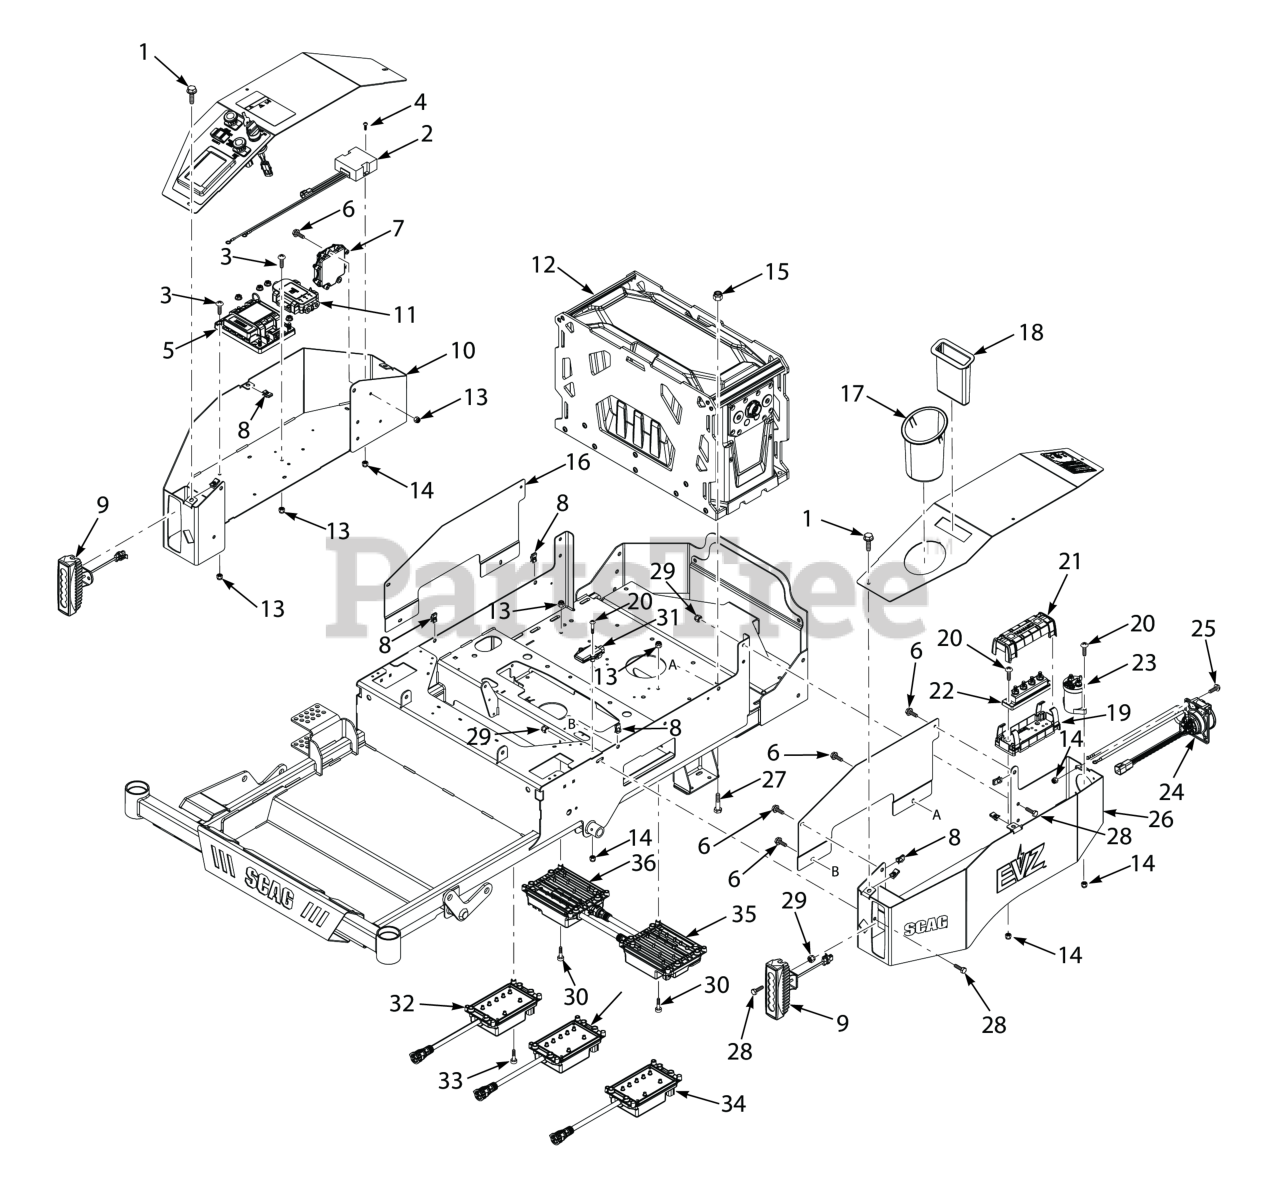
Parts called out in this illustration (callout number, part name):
1	Bolt, Hex Head Serrated Flange 1/4-20 x 3/4"
2	Converter, 48V to 12V
3	SCR, 1/4-20 X 1.0 PHIL RD HD
4	Screw, #8-32 x .75"
5	Bus Bar
6	Capscrew, 1/4-20 x 1"
7	Interface Module
8	Bolt, Hex Head 3/8-16 x 1"
9	Worklight, 48V LED
10	Console, RH
11	Fuse Module
12	Battery, 5 KW Vanguard
13	HEX, NUT, ELASTIC STOP LOCK, 1/4-20
14	HEX NUT, ELASTIC STOP LOCK # 10-32
15	HEX NUT, ELASTIC STOP LOCK, 3/8-16
16	Cover, Side RH
17	Cup Holder
18	Phone Holder
19	Bus Bar Assy, 4 Post (incl. 39 & 40)
20	Screw, #10-32 x 1.12" Phillips Head
21	Enclosure, Bus Bar
22	Bus Bar, 4 Post
23	Relay
24	Receptacle, Vehicle Plug
25	Screw, #10-32 x 3/4"
26	Console w/Decals, LH
27	Bolt, Hex Head 3/8-16 x 1-1/2" B&S 32BV
28	BOLT, SERRATED FLANGE HEX HEAD 5/16-18 X 3/4"
29	HEX NUT, ELASTIC STOP LOCK, 5/16-18
30	Cap Screw, Socket Head 1/4-20 x 1"
31	Blue Tooth, Smart Tec
32	Deck Controller, RH
33	Deck Controller, Center
34	Deck Controller, LH
35	Drive Controller, LH
36	Drive Controller, RH
